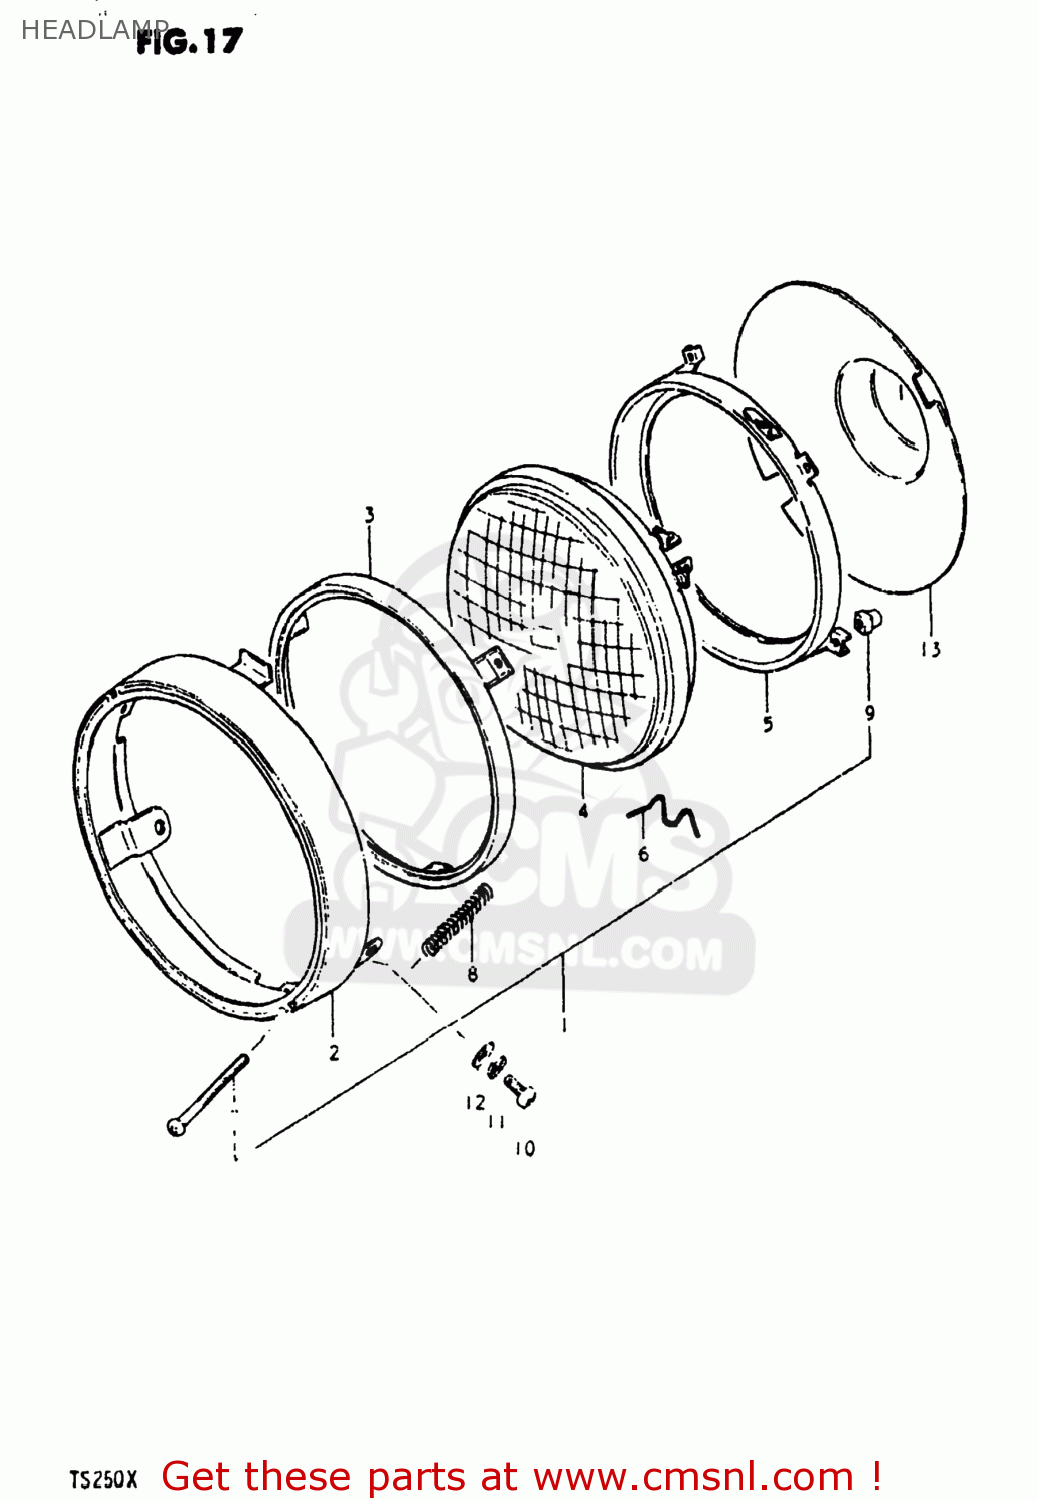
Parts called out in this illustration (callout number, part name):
1	LAMP ASSEMBLY,HEAD
2	RIM
3	RETAINER,HEADLAMP
4	LAMP UNIT
5	RING,HEADLAMP UNIT
6	SPRING,HEADLAMP UNIT
7	SCREW,HEADLAMP ADJUST
8	SPRING,ADJUSTING
9	NUT,HEADLAMP ADJUSTER
10	SCREW
11	LOCK WASHER
12	WASHER
13	COVER,HEADLAMP UNIT
